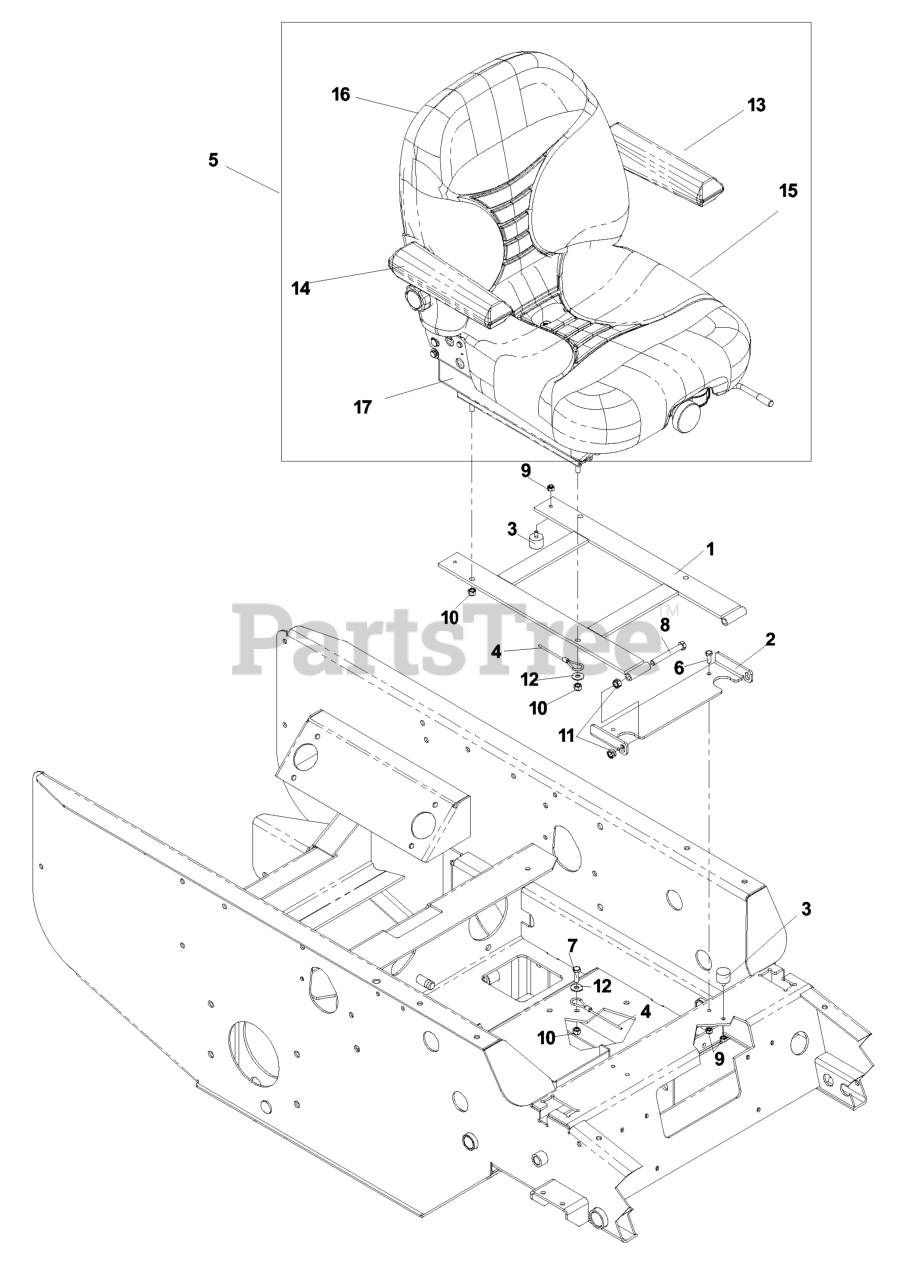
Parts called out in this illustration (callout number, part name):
1	SEAT MOUNT
2	SEAT BKT. W/PAINT
3	STUD/PLATE MOUNT
4	SEAT LANYARD
5	Seat suspension
6	HCS 1/4C X 3/4 HCS
7	HCS 5/16C X 1
8	HCS 3/8C X 3
9	NUT.1/4-20.HEX.NYLOC.ZD
10	NUT 5/16 NYLOC
11	NUT 3/8C CENTERBLOCK
12	WASHER 5/16 FLAT
13	ARMREST KIT, LH
14	ARMREST KIT, RH
15	SEAT CUSHION KIT
16	BACK CUSHION KIT
17	SLIDE KIT, SEAT ADJ
